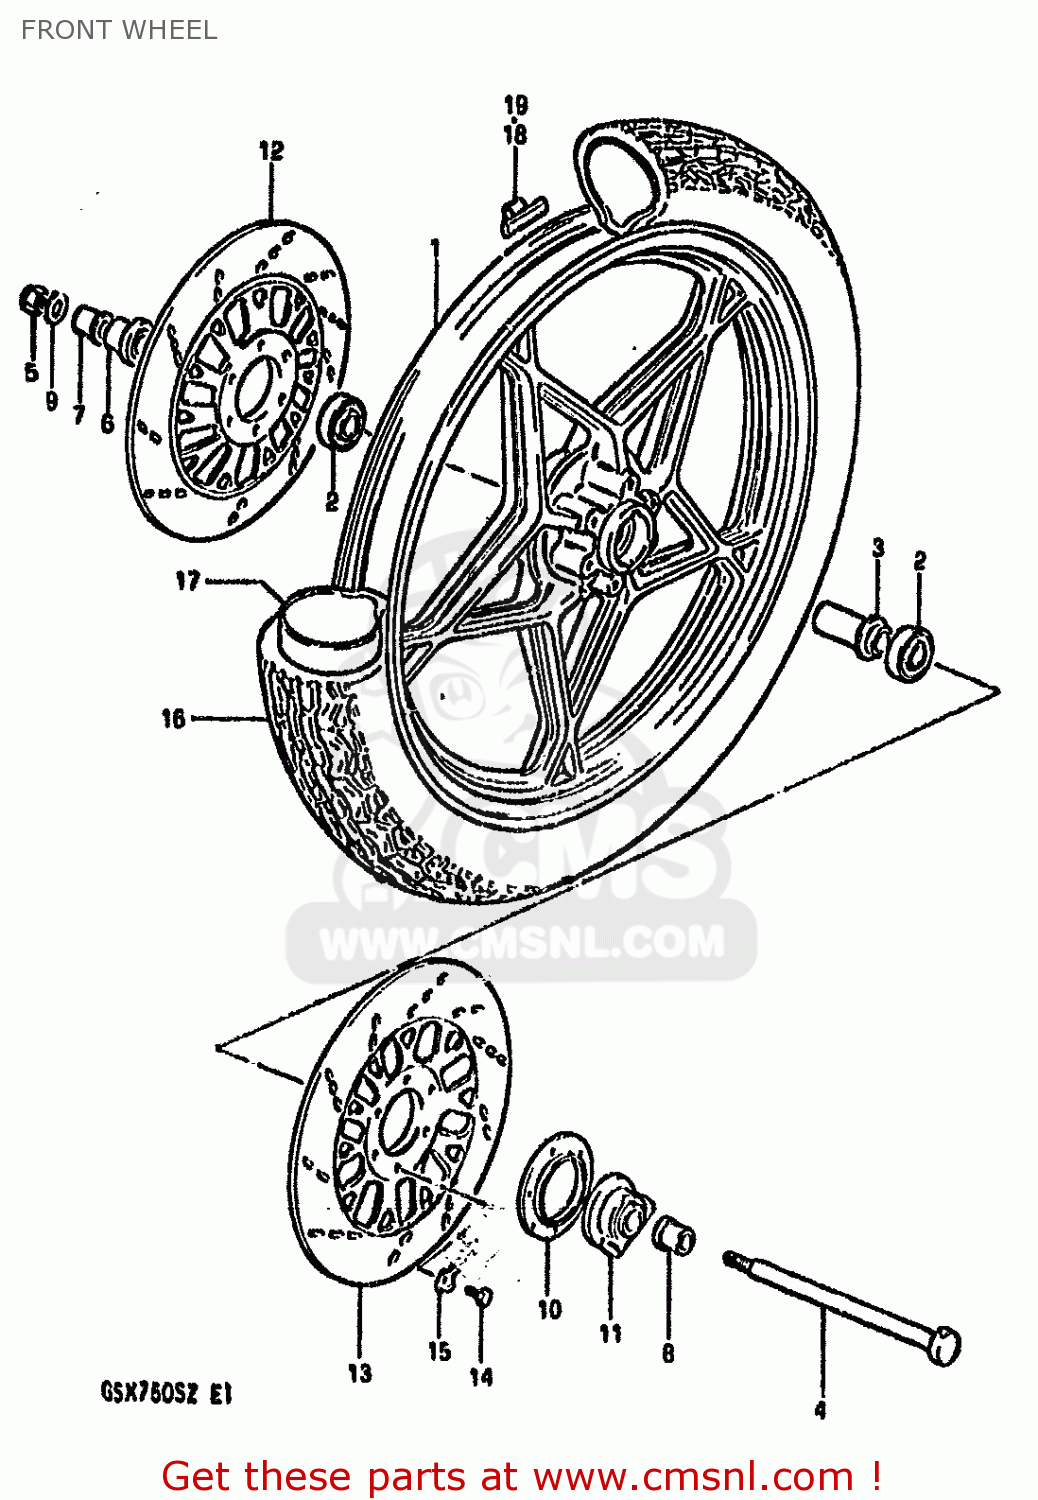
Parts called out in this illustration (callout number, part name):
1	WHEEL, FRONT (19X1.85) (GRAY)
2	BEARING
3	SPACER,FR HUB BEARING
4	AXLE,FR
5	NUT
6	SPACER,FR AXLE,R
7	SPACER,FR AXLE,R
8	SPACER,FR AXLE,L
9	WASHER
10	DUST SEAL,SPEEDOMETER GEAR BOX
11	BOX ASSEMBLY,SPEEDOMETER GEAR
12	DISC,FR BRAKE,R
13	DISC,FR BRAKE,L
14	BOLT(8X25)
15	WASHER
16	TIRE,FRONT
17	TUBE,INNER
18	BALANCER,WHEEL
19	BALANCER,WHEEL (30G)
